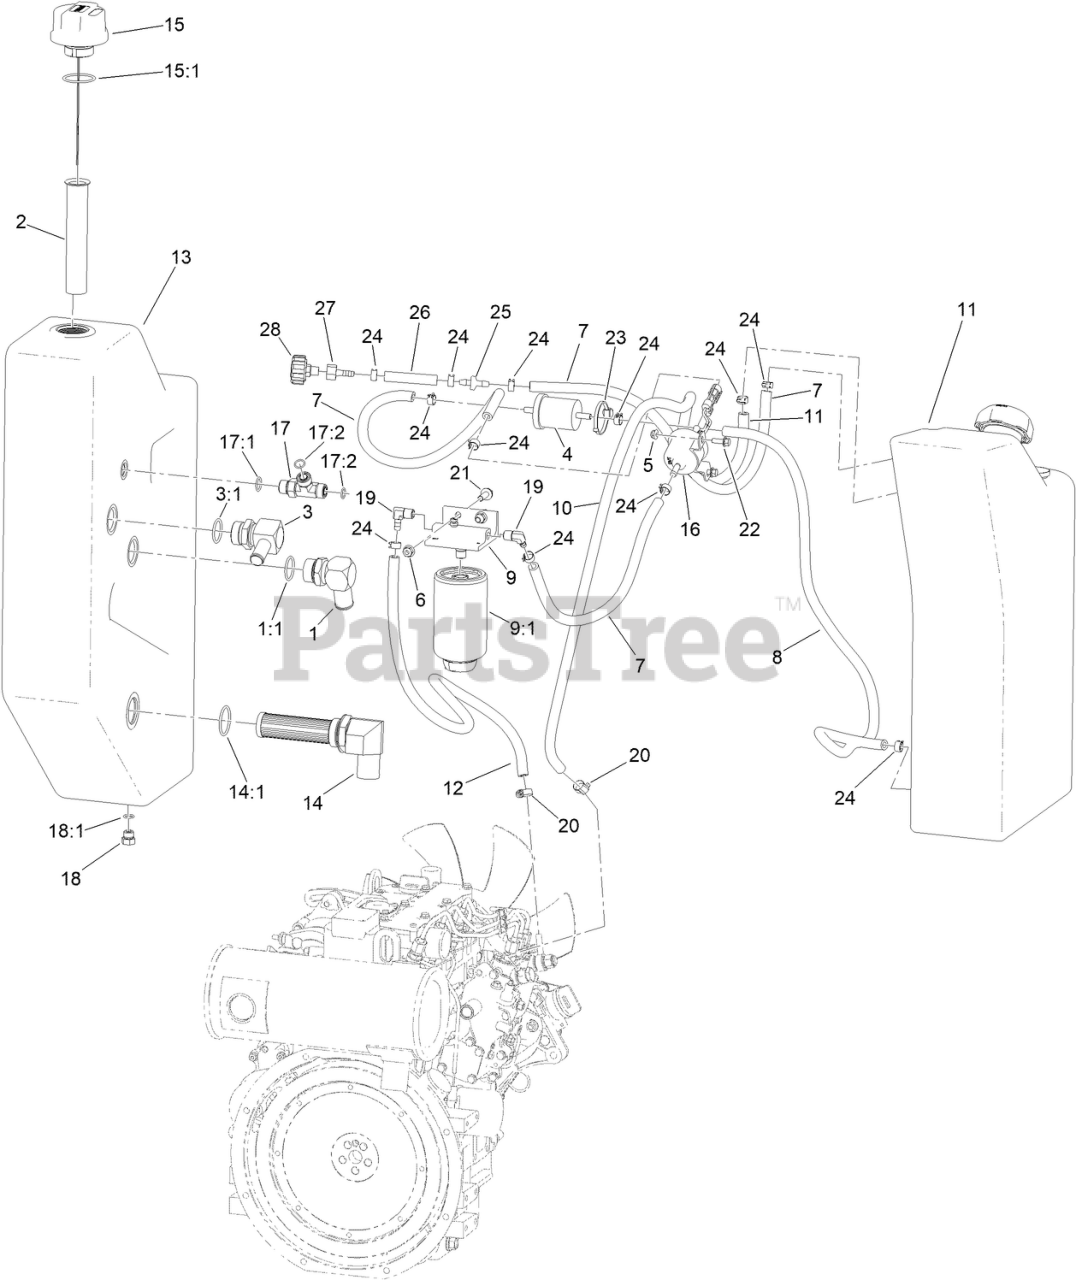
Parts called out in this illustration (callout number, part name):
1	STEM-BARB-90
1:1	O-RING
2	FILTER-SCREEN
3	FITTING-ELBOW, 90
3:1	O-RING
4	FILTER-FUEL
5	NUT-HF
6	NUT-HF, NI
7	HOSE-FUEL
8	HOSE-FUEL
9	SEPARATOR-FILTER
9:1	FILTER-SPIN ON
11	TANK ASM, LH
12	HOSE-FUEL
13	TANK-HYDRAULIC
14	STRAINER FITTING ASM
14:1	O-RING
15	CAP-FILLER, BREATHER
15:1	O-RING
16	PUMP-FUEL, ELECTRIC
17	FITTING-TEE
17:1	O-RING
17:2	O-RING
18	PLUG-HH
18:1	O-RING
19	FITTING-HYD, 90
20	CLAMP-WORM
21	SCREW-HHF
22	SCREW-HHF
23	CLIP-TIE
24	CLAMP-HOSE
25	VALVE-CHECK, FUEL
26	HOSE-FUEL
27	FITTING-STRAIGHT
28	BREATHER
